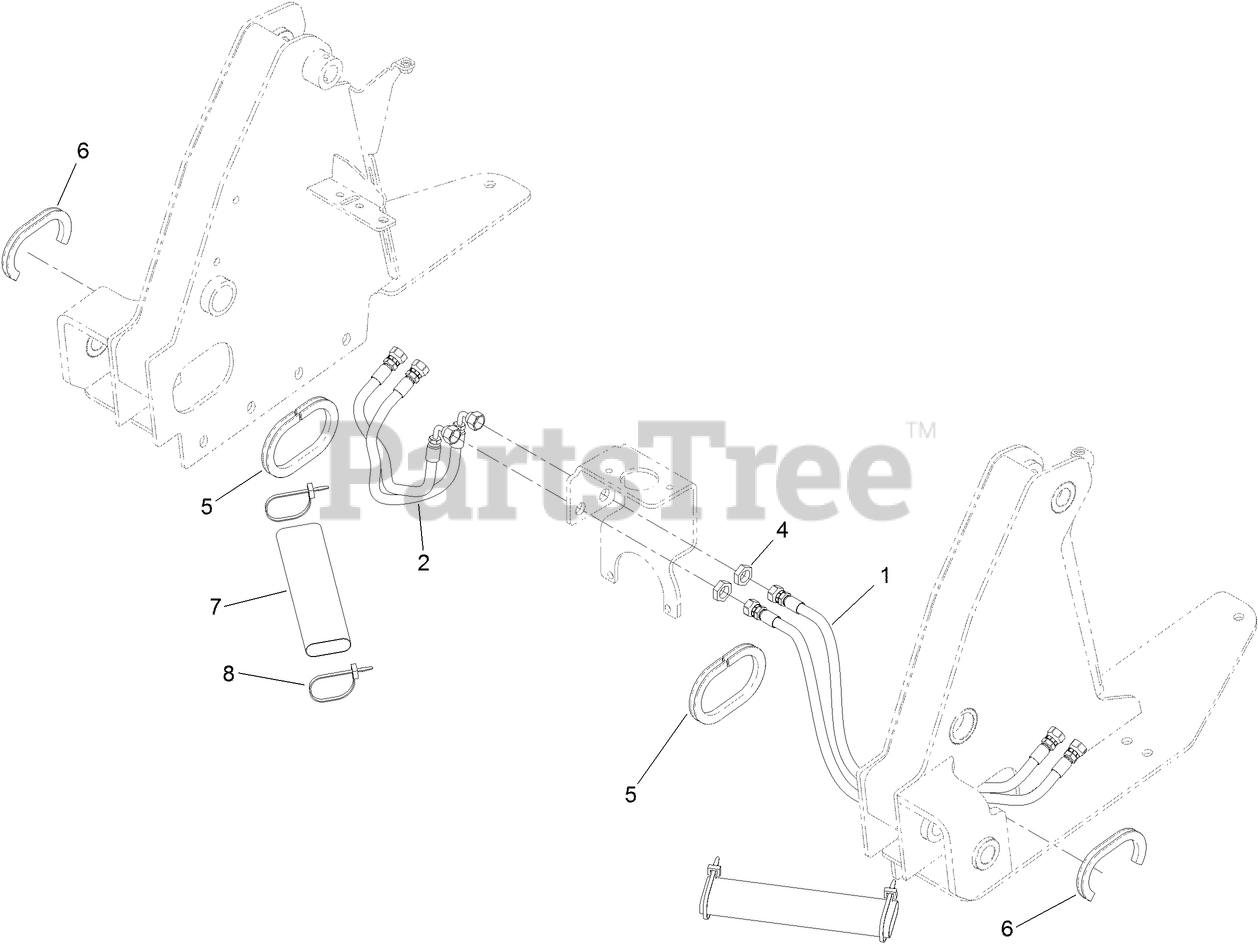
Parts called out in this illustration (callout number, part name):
1	HYD HOSE ASM
2	HYD HOSE ASM
4	NUT-LOCK
5	TRIM-SEAL
6	TRIM-SEAL
7	SLEEVE-PROTECTIVE
8	TIE-CABLE
